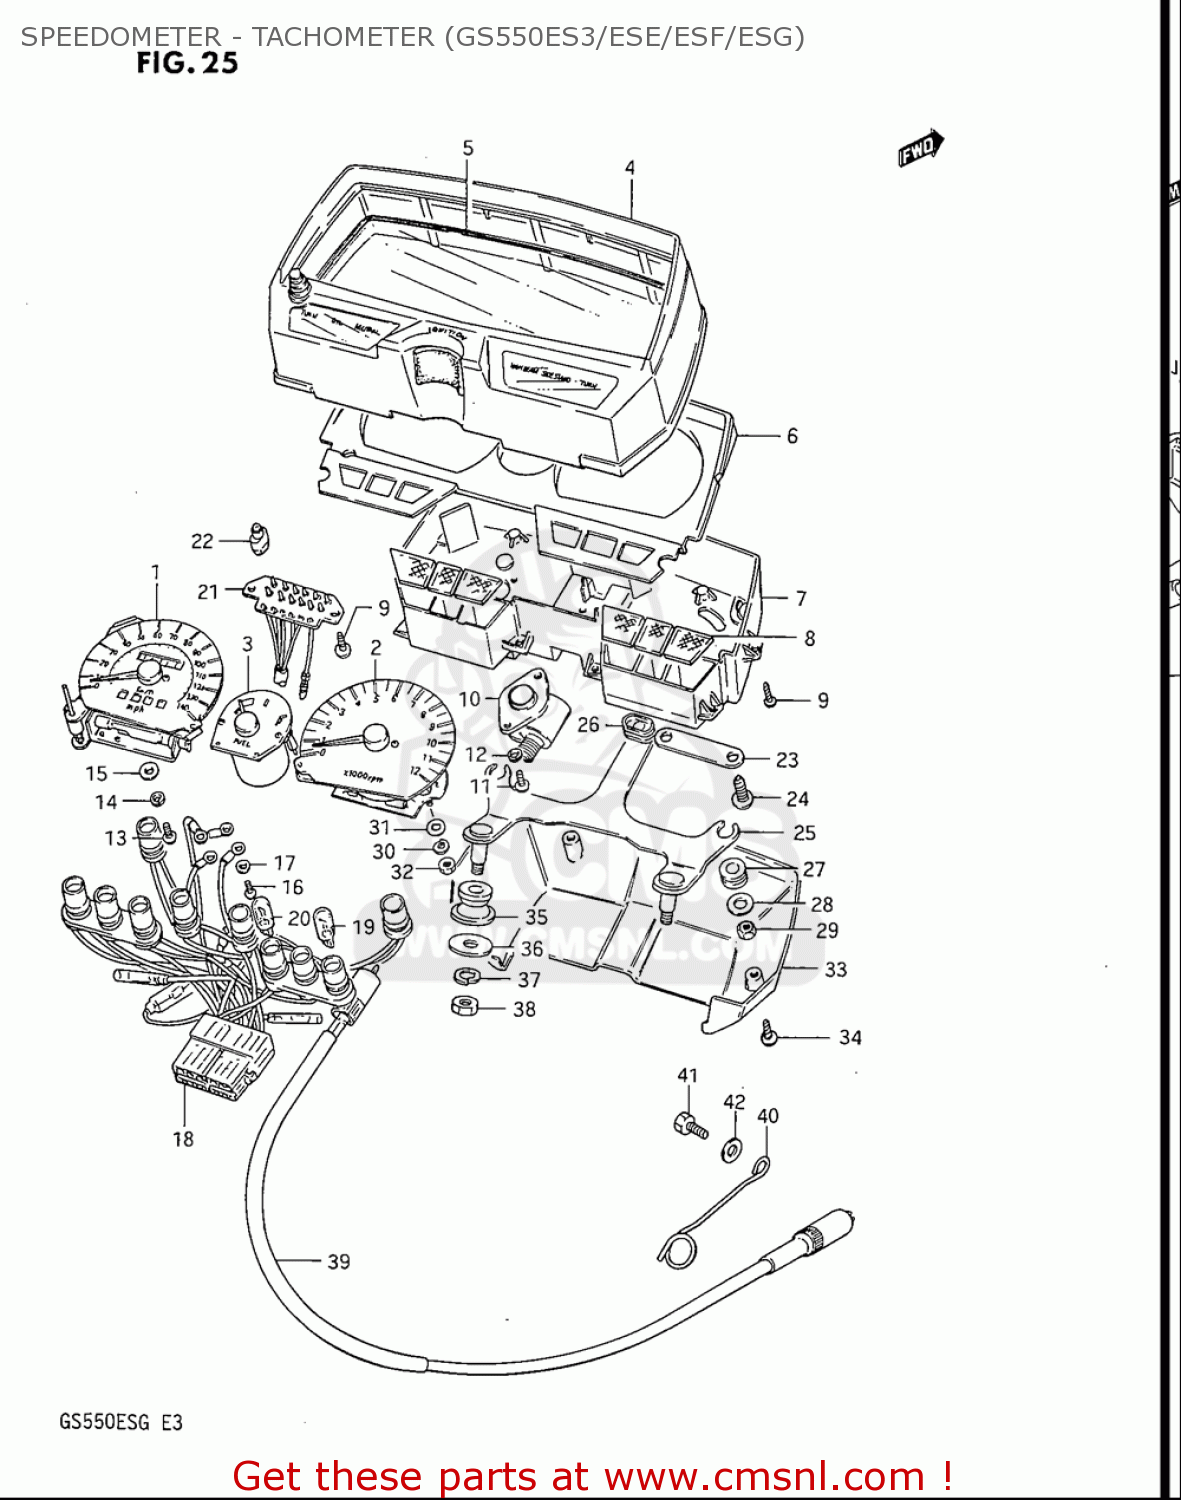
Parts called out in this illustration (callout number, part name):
4	HOOD,METER
5	GLASS,SPEEDOMETER
7	CASE,METER,INNER
9	SCREW,GEAR INDICATOR
11	SCREW
12	WASHER,LOCK
13	SCREW
14	WASHER,LOCK
15	WASHER
16	SCREW
17	WASHER
19	BULB(12V3.4W,T10,BF175-01450A)
20	BULB(12V1.7W,T10,WB121)
22	BULB(14V1.12W)
24	SCREW
26	CUSHION,METER
27	CUSHION,METER
28	WASHER(5.5X16X1.2)
29	NUT
30	WASHER,LOCK
32	NUT
34	SCREW
35	CUSHION,METER BRACKET
36	WASHER(8.5X28X1.6)
37	WASHER,LOCK
38	NUT
39	CABLE ASSY,SPEEDOMETER
40	CLAMP,SPEEDOMETER CABLE
41	BOLT
42	WASHER
